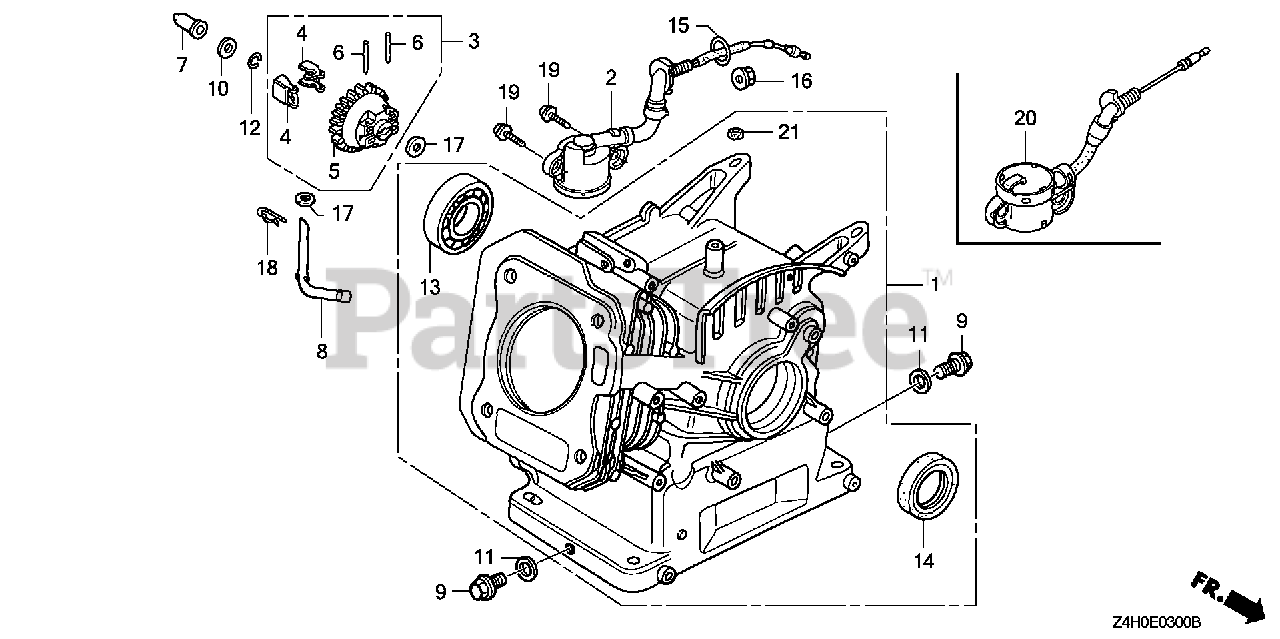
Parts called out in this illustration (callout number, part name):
1	CYLINDER ASSY. (OIL ALERT)
2	SWITCH ASSY., OIL LEVEL
3	GOVERNOR ASSY.
4	WEIGHT, GOVERNOR
5	HOLDER, GOVERNOR WEIGHT
6	PIN, GOVERNOR WEIGHT
7	SLIDER, GOVERNOR
8	SHAFT, GOVERNOR ARM
9	BOLT, DRAIN PLUG
10	WASHER, THRUST (6MM)
11	WASHER, DRAIN PLUG (10.2MM)
12	CLIP, GOVERNOR HOLDER
13	BEARING, RADIAL BALL (62/22)
14	OIL SEAL (22X35X6)
15	O-RING (14MM) (ARAI) Use up to Engine SN 2949254.
15	O-RING (14MM) (NOK)
16	NUT, FLANGE (10MM)
17	WASHER, PLAIN (6MM)
18	PIN, LOCK (8MM)
19	BOLT, FLANGE (6X12) Use up to Engine SN 1543277.
20	SWITCH ASSY., OIL LEVEL
